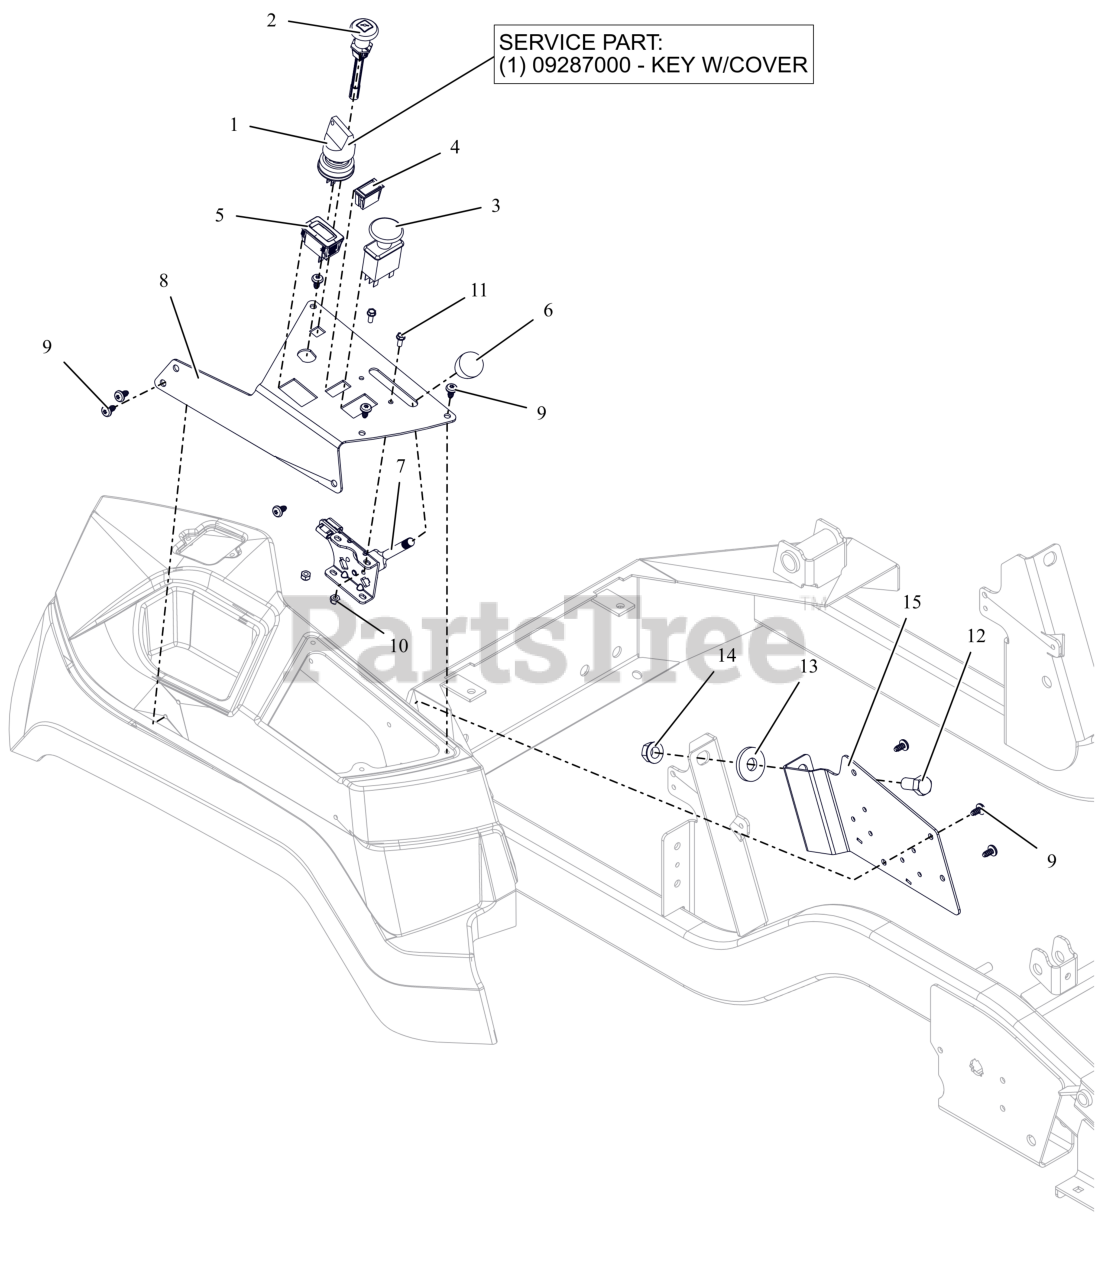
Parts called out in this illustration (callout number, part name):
1	SWITCH, IGNITION
1	KEY, W/ SHIELD
2	CABLE - CHOKE, SNAP-IN
3	SWITCH, CLUTCH
4	SWITCH,BLANK
5	HOUR METER
6	KNOB-CONTROL-BLACK .38-16X.50
7	CABLE, PRO THROTTLE CONTROL
8	PLATE, APEX CONTROL PANEL
9	SCR-PAN .25-15X.50 6L H/LZB500
10	NUT-LK-NYL #10-24 G2 ZCC
11	BLT, HWH #10-24X.50 ZCC
12	BLT, HEX .50-13X1.00 G5 ZCC
13	WSHR-FL-STL 0.562X1.5X0.187 ZCC
14	NUT-LK-CTR-FLG .500-13 GG ZCC
15	BRKT, FENDER/RELAY MOUNTING
